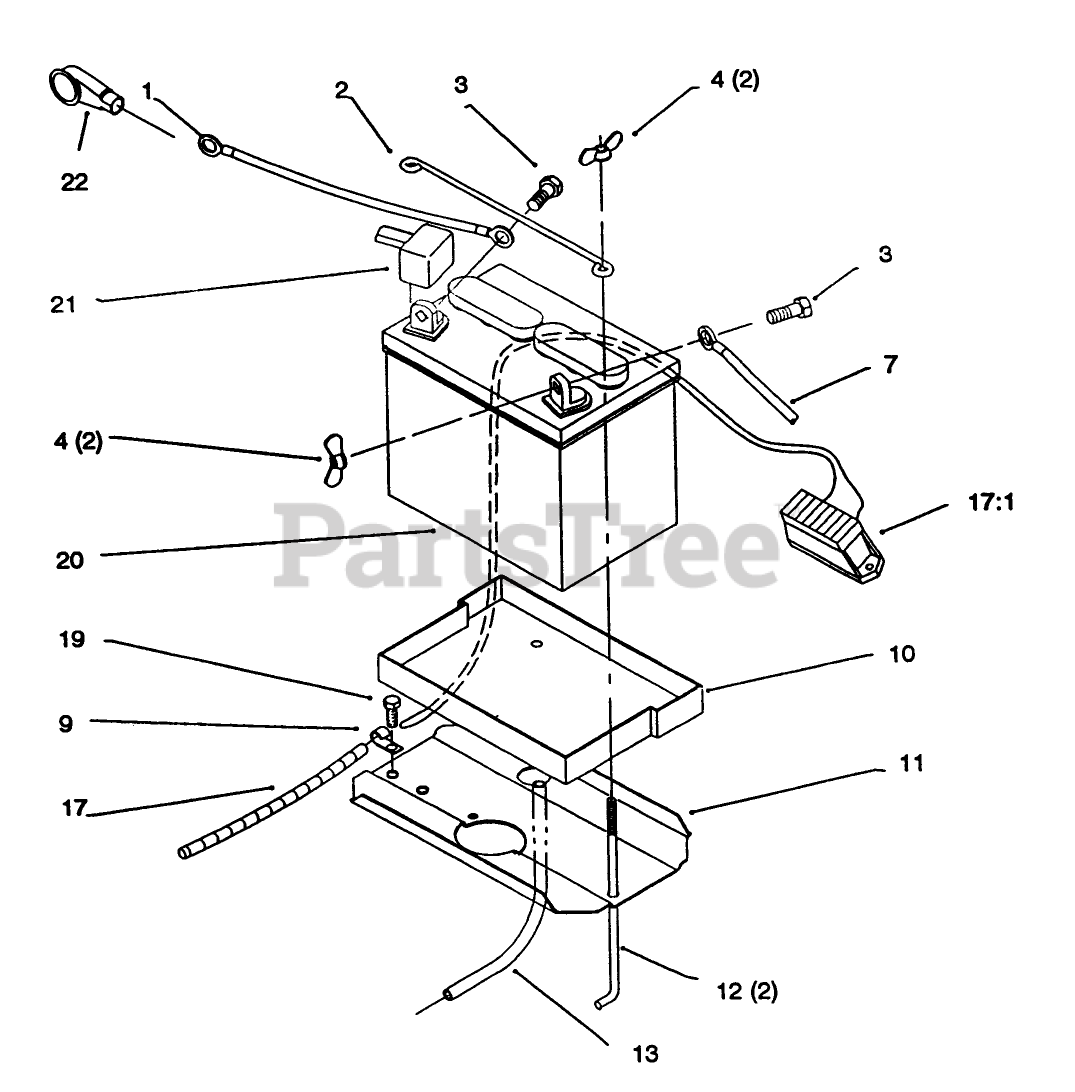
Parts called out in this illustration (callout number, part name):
1	WIRE-21 INCH
1	WIRE -10" RED
2	ROD-BATTERY HOLD DWN
3	SCREW-HH
4	NUT-WING
7	WIRE -BLACK
7	CABLE
9	CLIP
10	TRAY-BATTERY
11	PLATE-BATTERY
13	TUBE-21" BATTERY DRAIN
17	WIRE HARNESS
19	SCREW-HWHTF
22	BOOT-INSULATOR, TERMINAL
